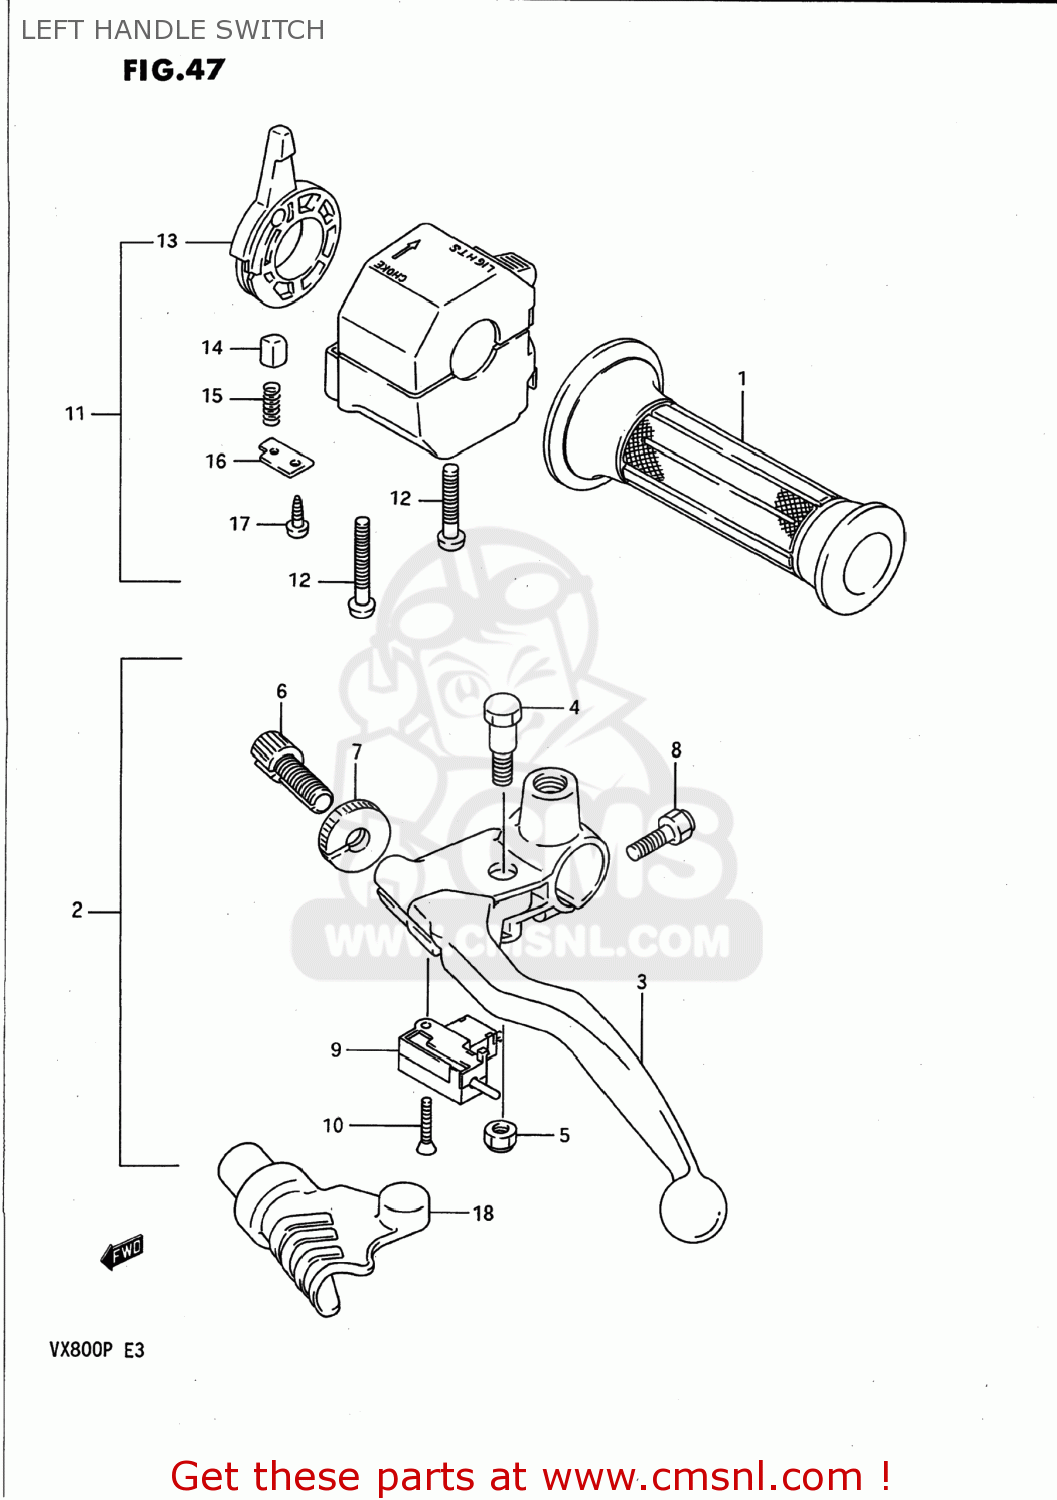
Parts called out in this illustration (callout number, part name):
1	GRIP,L
2	LEVER ASSEMBLY
3	LEVER,CLUTCH
4	BOLT,LEVER SET
5	NUT
6	ADJUSTER,WIRE
7	NUT,LOCK
8	BOLT 6X20
9	SWITCH,CLUTCH
10	SCREW
11	SWITCH ASSEMBLY,HANDLE,LEFT
12	SCREW, 5X45
13	LEVER,CHOKE
14	PIECE,SLIDE
15	SPRING
16	PLATE
17	SCREW
18	COVER,CLUTCH LEVER
